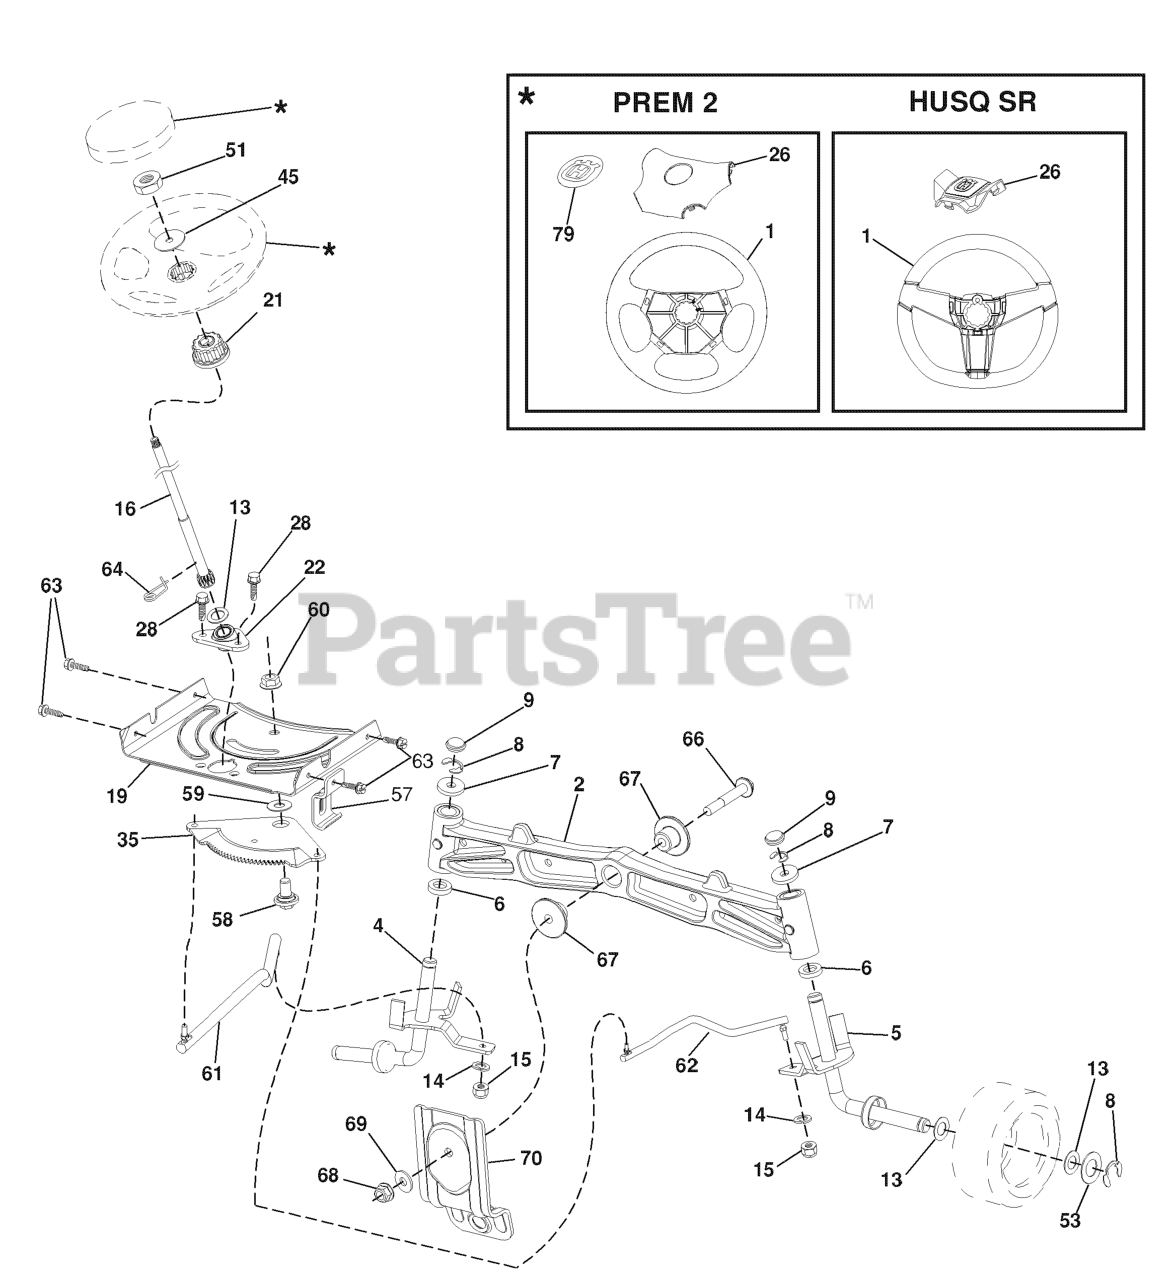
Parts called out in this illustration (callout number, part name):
1	RP WHEEL.STEER.HUSQ.PREM.OVMLD
2	AXLE.CAST.IRON
4	SPINDLE.WELDED.LH.15"TEX
5	SPINDLE.WELDED.RH.15"T
6	THRUST WASHER
9	CAP.SPINDLE.BLACK
14	WASHER, LOCK 3/8
15	NUT CROWNLOCK 3/8-24
16	SHAFT, STEERING
19	PLATE.STEER.DDL.NLT/NG
21	ADAPTER, WHEEL STNG..
22	BUSHING.ASM.STEERING.A
26	RP INSERT.CAP.WHL.STRG.HUSQ.
28	SCREW, 3/8-16X3/4
35	GEAR.SECTOR.PLATE.DDL.
45	WASHER 9/16"ID, 2 3/8"OD
51	NUT.HEX.1/2-20
53	WASHER.HARDENED
57	BRKT.UPSTOP.GT/LT.TEX
58	BOLT.SHOULDER.SECTOR.P
59	WASHER.THURST.SECTOR.S
60	NUT FLANGE LOCK 5/8-11
61	DRAGLINK.LH.BALLSTUD.D
62	DRAGLINK.RH.BALLSTUD.D
63	SCREW
64	RETAINER.CLIP.SPRING.S
66	BOLT HEX FGHD 7/16-14 X 3 SERR
67	BUSHING.PM.FRONT AXLE
68	NUT.LOCK.FLANGE.7/16
69	WASHER.1.5X.505X.118
70	BRKT.DECK.SUSPENSION.F
